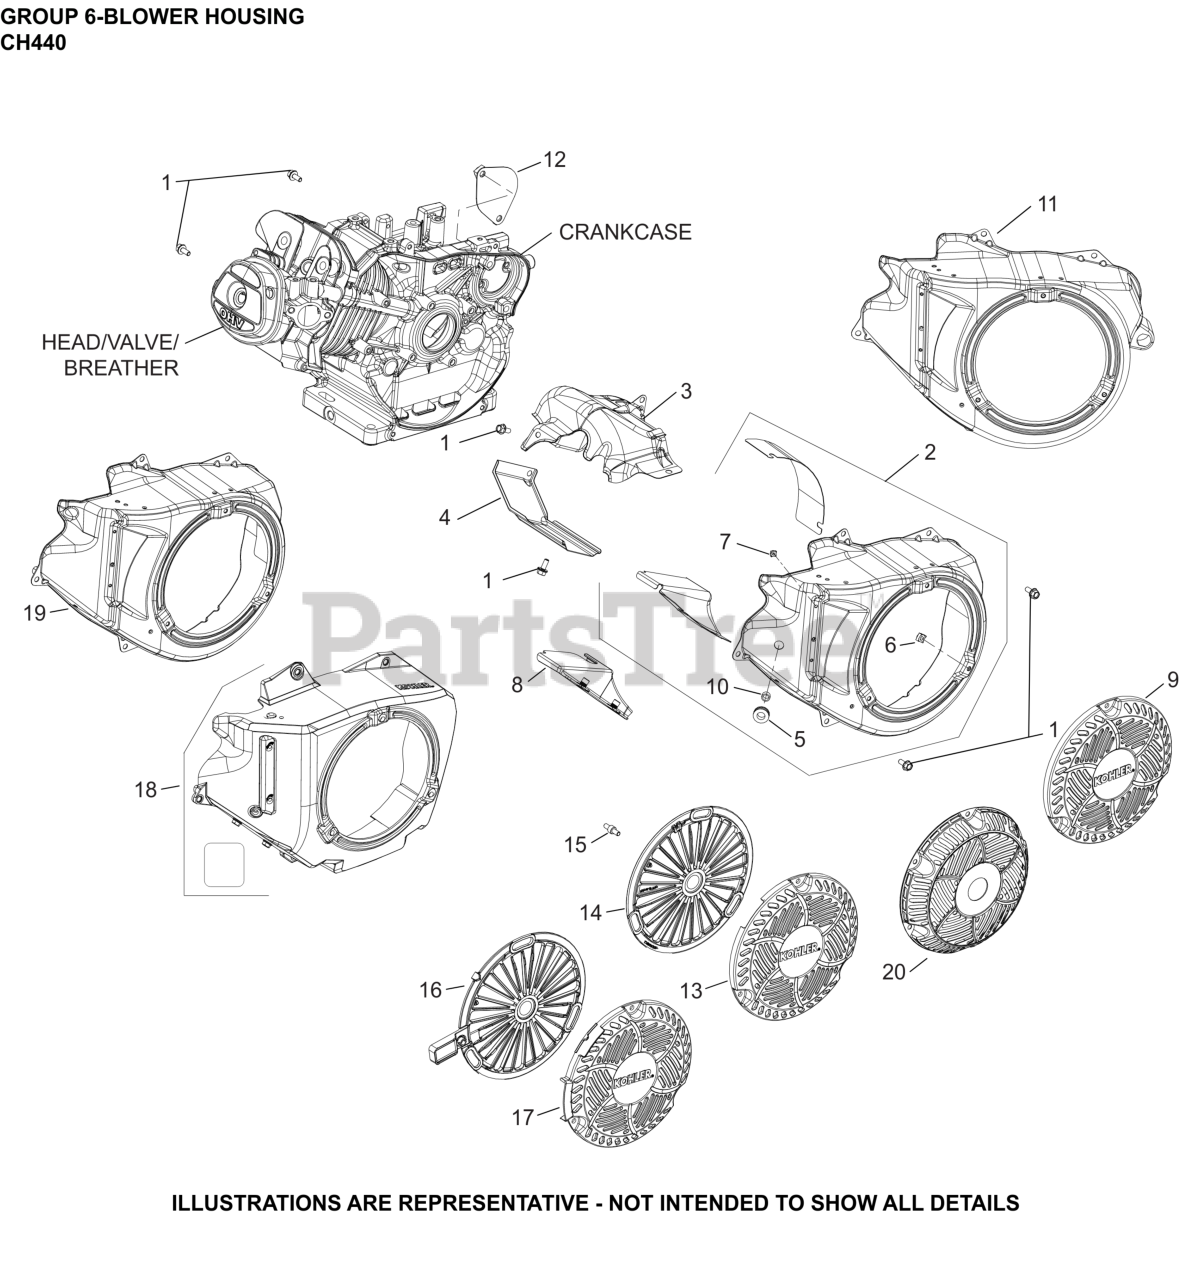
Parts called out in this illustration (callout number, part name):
1	SCREW, HEX FLANGE (M6)-USE 25 086 433-S
2	HOUSING, BLOWER ASSEMBLY-USE 17 027 56-S
3	SHIELD, UPPER HEAT
4	SHIELD, CYLINDER HEAD
